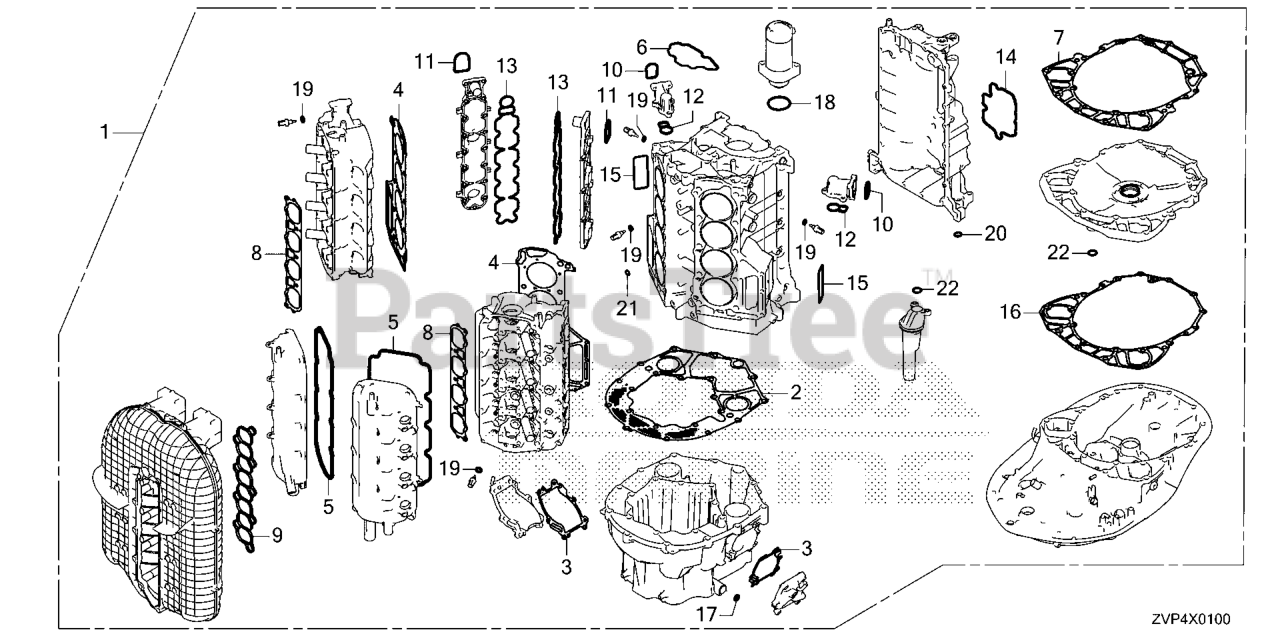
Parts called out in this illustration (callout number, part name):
1	GASKET KIT (BF350)
2	PKG, OIL PAN
3	GSKT, OIL CASE COVER
4	GASKET COMP
5	PKG, HEAD COVER
6	PKG
7	PKG, OIL PUMP BODY
8	GSKT, INJ BASE
9	PKG, IN MNFLD
10	PKG
11	PKG
12	PKG, THERMOSTAT CASE
13	PKG, W/J COVER
14	PKG, W/J COVER F
15	PKG, W/J SIDE COVER
16	GSKT, MOUNT CASE
17	WASHER, DRAIN PLUG (12MM)
18	O-RING (59.4X3.1)
19	O-RING (9.5X1.9)
20	O-RING (18X2.4)
21	O-RING (13X1.5) (ARAI)
22	O-RING (20.6X2.6)
